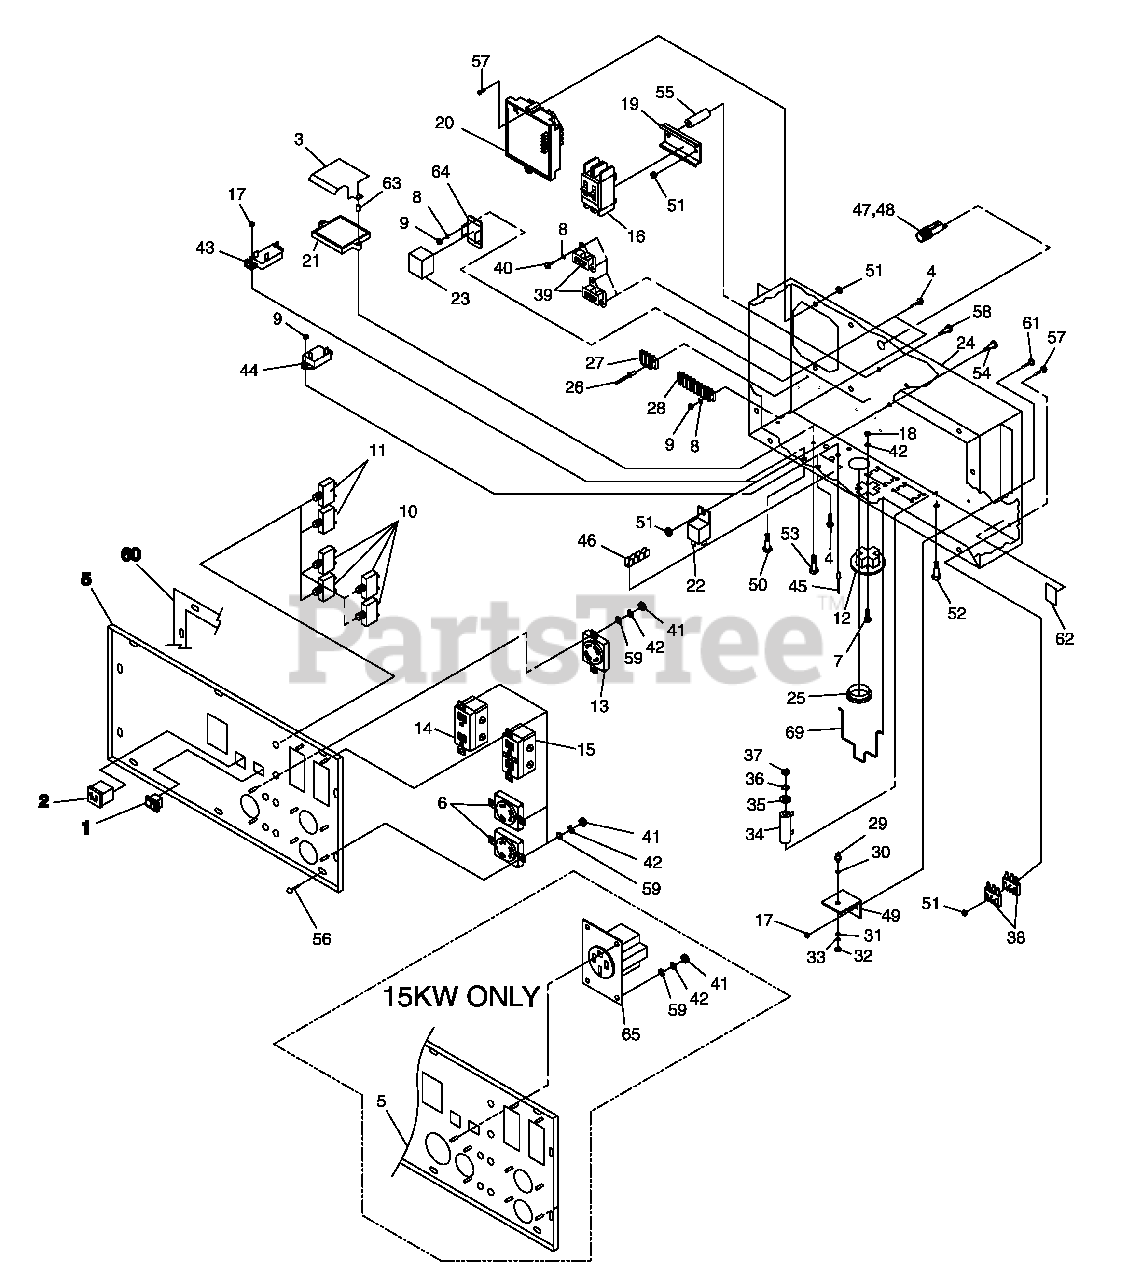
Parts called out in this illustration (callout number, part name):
1	SWITCH, ROCKER -/0
2	OUTLET, 12VDC SNAP
3	COVER, GOVERNOR CONTROL
4	SCREW PPHM M3-0.5 X 12
5	PANEL, SHEET METAL (15 KW)
6	OUTLET 30A 120V RECEPT
7	SCREW SFILHM #8-32 X 5/8 LG (17.5 KW ONLY)
8	NUT HEX LOCK M3-0.5 NY INS
9	CIRCUIT BREAKER 30A
10	CIRCUIT BREAKER 20A
11	OUTLET 50A 250V (17.5 KW ONLY)
12	OUTLET 30A 125/250V
13	OUTLET 20A 120V DPLX
14	OUTLET 20A 120V GFCI
15	CIRCUIT BREAKER 50A 400V 2POLE
16	NUT HEX M4-0.5 NYINS
17	NUT HEX #8-32 (17.5 KW ONLY)
18	DIN RAIL 59.5mm LONG
19	ASSY PCB VREG AIR COOLED
20	ELECTRONIC GOVERNOR / IDLE CONTROLLER
21	RELAY PNL 12VDC SPST 30A
22	RELAY 3PDT 12VDC
23	CONTROL PANEL BOX (15 KW)
24	CONTROL PANEL BOX (17.5 KW)
25	BUSHING SNAP
26	RIVET POP .156 X .160-.164 / #20
27	BLOCK TERMINAL 20A 2 X 6 X 1100V
28	BLOCK DOUBLE ROW TERMINAL 8 POSITION
29	RECTIFIER MSC 12A 600V
30	WASHER MICA .203
31	WASHER STEP NYLON .20
32	NUT HEX #10-32
33	WASHER FLAT #10
34	RESISTOR 25R 5% 25W
35	WASHER FLAT 1/4
36	WASHER LOCK M6-1/4
37	NUT HEX M6-1.0 G8
38	RECTIFIER-BATTERY CHARGER
39	TRANSFORMER, IDLE CURRENT
40	SCREW PPHM M3-0.5 X 8
41	NUT HEX M4-0.7 G8 (15 KW)
42	WASHER LOCK M4
43	CIRCUIT BREAKER 6 X 1
44	CIRCUIT BREAKER 10 X 1 12VDC 1/4"QC
45	RIVET POP .125 X .250 SS
46	LUG GROUND 8 TABS
47	HOLDER FUSE
48	FUSE 10A X AGC10
49	HEATSINK
50	SCREW PPHM M4-0.7 X 10
51	NUT HEX LOCK M5-0.8 NYINS
52	SCREW HHC M6-1.0 X 65 G8.8
53	SCREW HHC M5-0.8 X 25 G8.8
54	SCREW HHC M5-0.8 X 10 G8.8
55	SPACER .25 X .50 X 2.5 (17.5 KW)
56	SCREW HHTT M5-0.8 X 10
57	SCREW PPHM M5-0.8 X 30
58	SCREW PPHM M5-0.8 X 80 (17.5 KW)
59	WASHER FLAT #8 (15 KW)
60	GASKET, PORTABLE CONTROL PANEL
61	SCREW PPHM M4-0.7 X 16
62	TAPE ELEC UL PERMACEL
63	NUT TRIC M5-0.8
64	RELAY BASE 3PDT 12VDC
65	OUTLET 50A 125/250V (15 KW ONLY)
69	SPRING RETAINER
